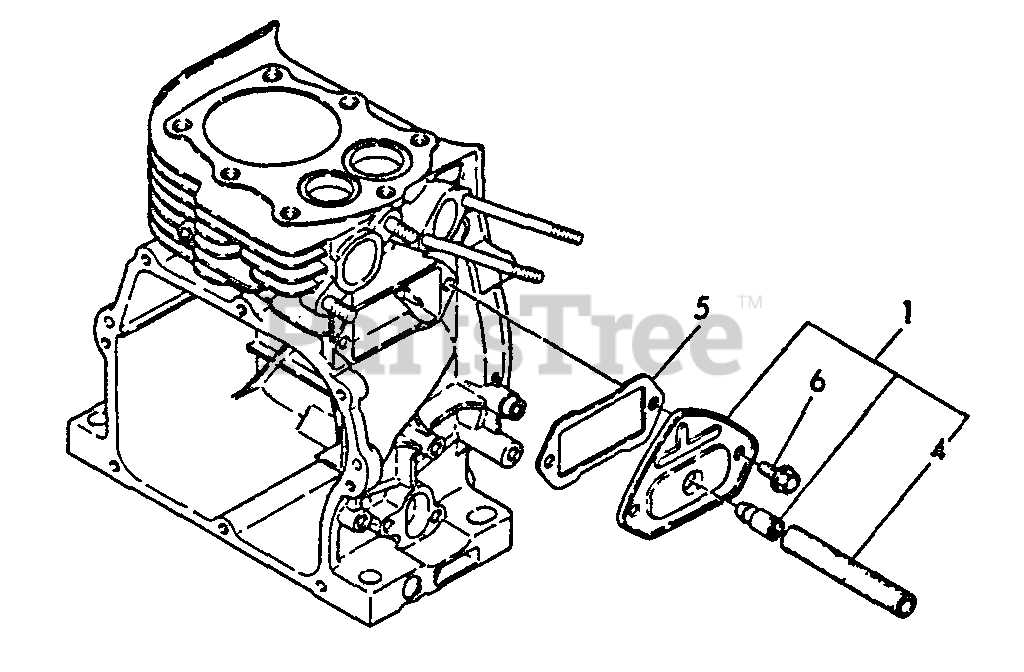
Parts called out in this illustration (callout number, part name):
1	BREATHER ASSY
4	PIPE, BREATHER
5	GASKET
6	BOLT - 6×8 -- PLATED
